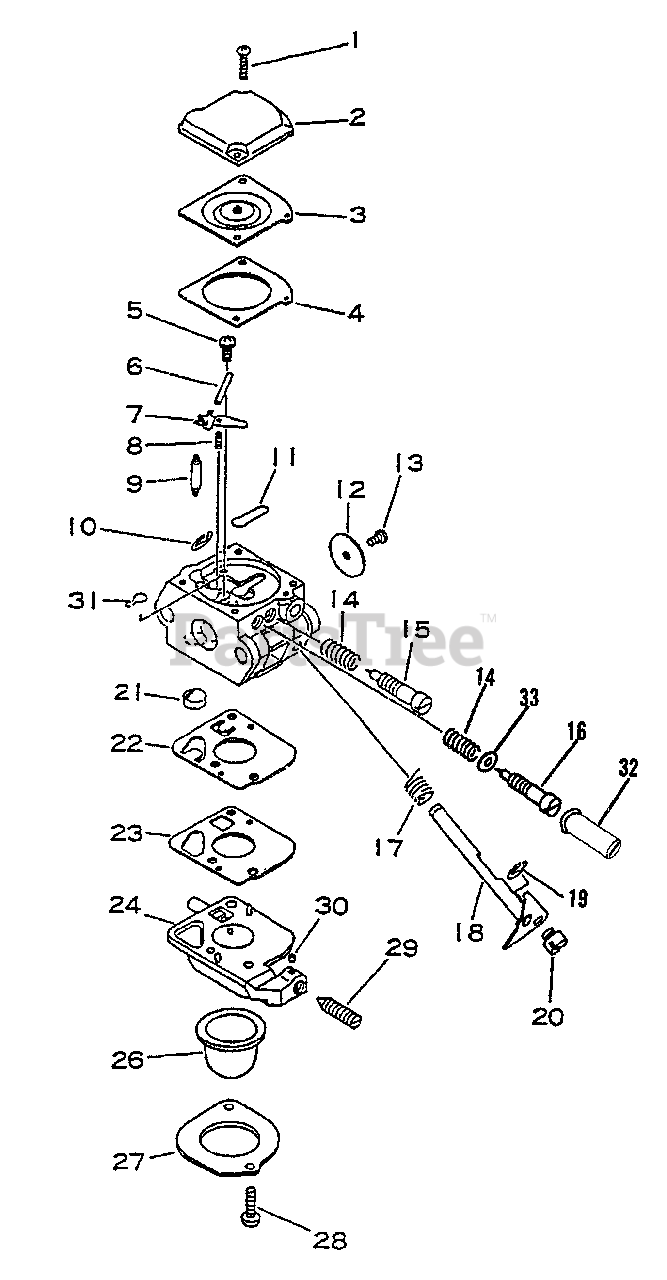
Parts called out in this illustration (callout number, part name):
2	COVER, METERING
3	DIAPHRAGM
4	GASKET, DIAPHRAGM
5	SCREW, METERING LEVER PIN
6	PIN, METERING LEVER
7	LEVER, METERING
8	SPRING
9	VALVE, NEEDLE
10	RING, RETAINING
11	PLUG, WELCH
12	VALVE, THROTTLE
15	NEEDLE - LOW SPEED
16	NEEDLE - HIGH SPEED
17	SPRING, RETURN
18	SHAFT, THROTTLE
19	RING, RETAINING
21	STRAINER
22	DIAPHRAGM, PUMP
23	GASKET, PUMP
24	BASE, PURGE
26	BULB, PURGE
27	RETAINER, PURGE BULB
28	SCREW, RETAINER
29	SCREW, IDLE ADJUST
30	PIECE, FRICTION
31	PLUG, WELCH
32	CAP, LIMITER
